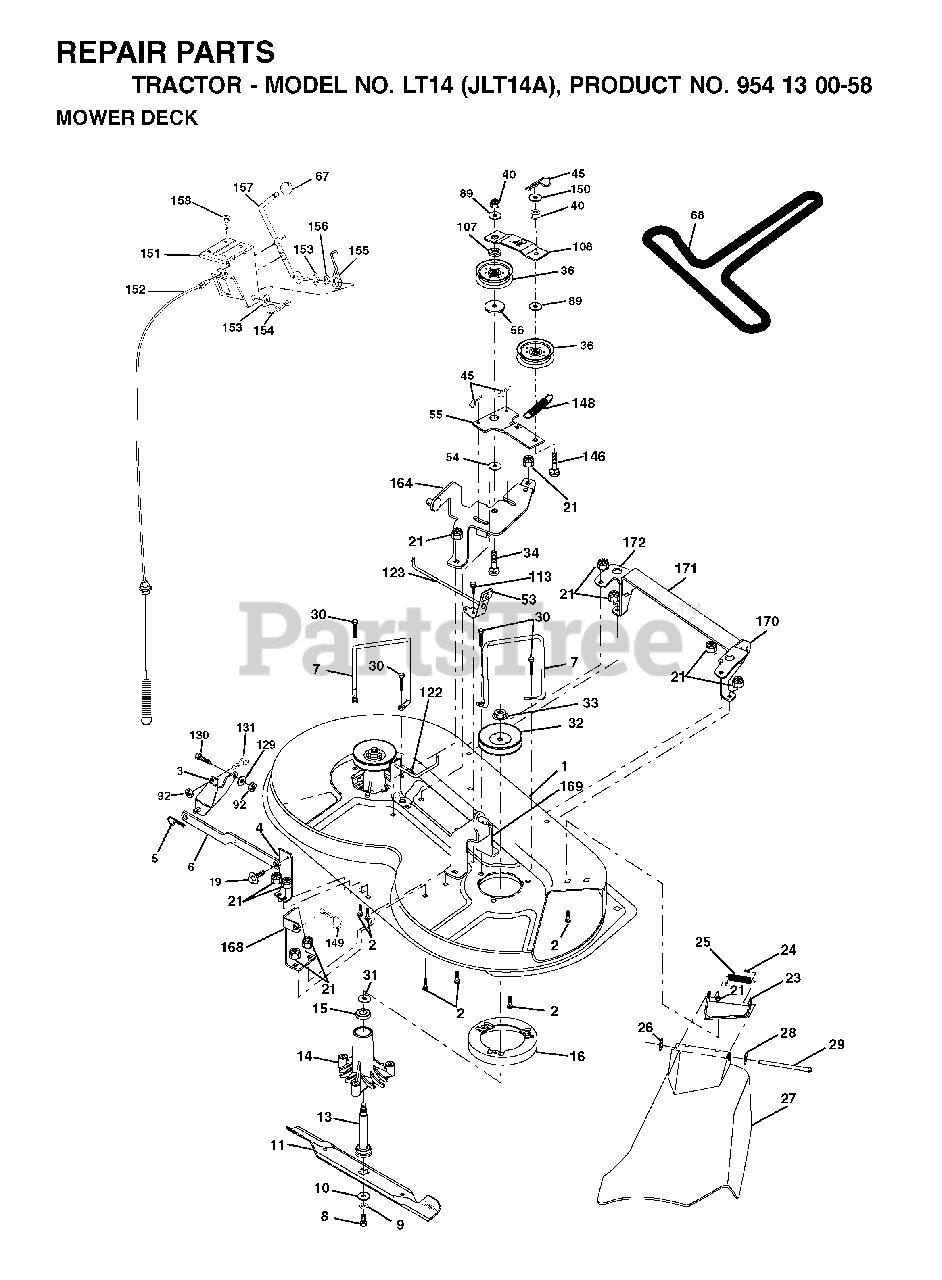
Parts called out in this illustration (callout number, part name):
2	BOLT
3	BRKT ASM SWAY BAR
5	RETAINER-SPRNG RB
6	BAR SWAY DECK
7	KEEPER LH
8	BLADE BOLT
9	LOCKWASHER
10	WASHER.BLADE
11	BLADE, HI-LIFT 36" PREMIUM
13	SHAFT ASM VENT
14	HSG MANDREL
16	STRIPPER, MWR ROUND
19	BOLT SHD 5/16-18
21	LOCKNUT
23	BRACKET ASM DEFLECTOR
24	CAP-SLEEVE LT
25	SPRING TORSION
26	NUT PUSH M
28	WASHER
29	HINGE ROD
30	SCREW, WASHER HEAD
31	WASHER
32	PULLEY, MANDREL
33	NUT, FLG TOPLOCK 9/16"
34	BOLT
36	FLAT IDLER PULLEY
40	LOCKNUT
45	RETAINER M
53	BRAKE ASSEMBLY
54	HARDENED WASHER
55	IDLER ARM
56	SPACER.RETAINER.MOWER
67	KNOB T (3/8 HOLE)
68	V-BELT.MOWER.
89	WASHER GT
92	NUT
107	SPACER.IDLER.ARM
108	STIFFENER.IDLER.ARM
129	WASHER
131	BOLT D
146	BOLT, CARRIAGE IDLER
148	IDLER RETURN SPRING
149	SPRING.RETAINER.YELLOW.ZINC
150	WASHER PM
151	BRACKET, CLUTCH CABLE
153	WASHER FLAT 3/8"
154	SPRING RETAINER
155	SPRING RETENTION LEVER
156	SPACER CLUTCH CABLE
157	ROD CLUTCH CABLE 3/8"
158	SCREW LT
171	BRACE
